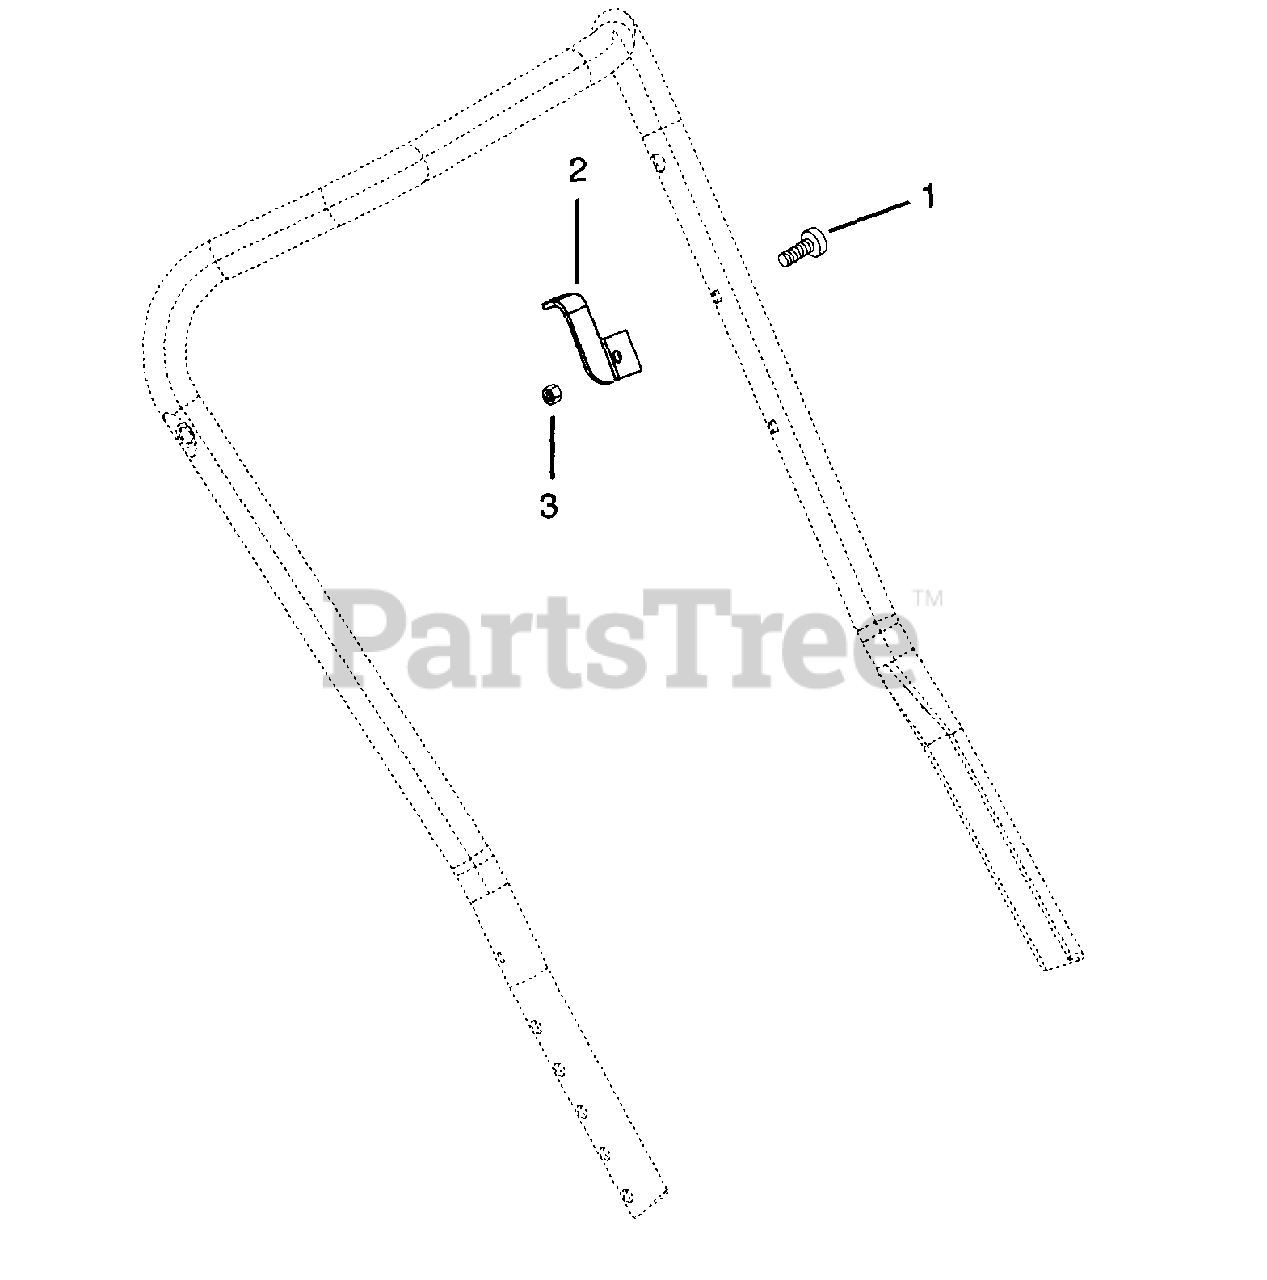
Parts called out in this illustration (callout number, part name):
1	BLT-RDHDSQNK .25-20X1.25 XLGPL
2	CABLE ANCHOR
3	NUT-LK-FLG .250-20 PL BLK
